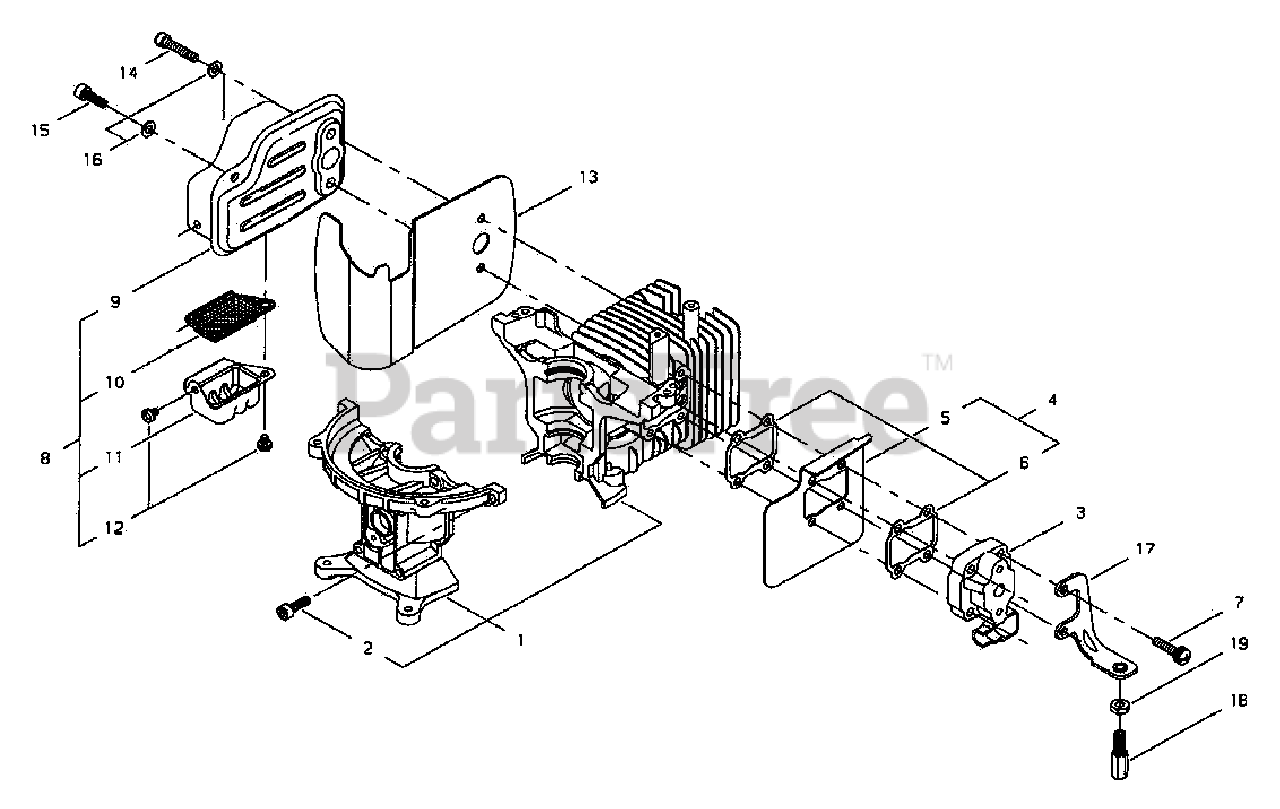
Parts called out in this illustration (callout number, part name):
1	CYLINDER BLOCK SET
2	SCREW - 5X16
3	INSULATOR
4	HEAT DEFLECTOR ASSY
5	DEFLECTOR, HEAT
6	SHIELD, INTAKE
7	SCREW - 5X22
8	MUFFLER ASSY
9	MUFFLER
10	SCREEN, SPARK ARRESTOR
11	GUIDE, EXHAUST
12	SCREW - 4X6
13	SHIELD, EXHAUST
14	SCREW - 5X25
15	SCREW - 5X16
16	WASHER - 5
17	BRACKET, CABLE
18	NUT, CABLE ADJUST
19	LOCKNUT - 6
